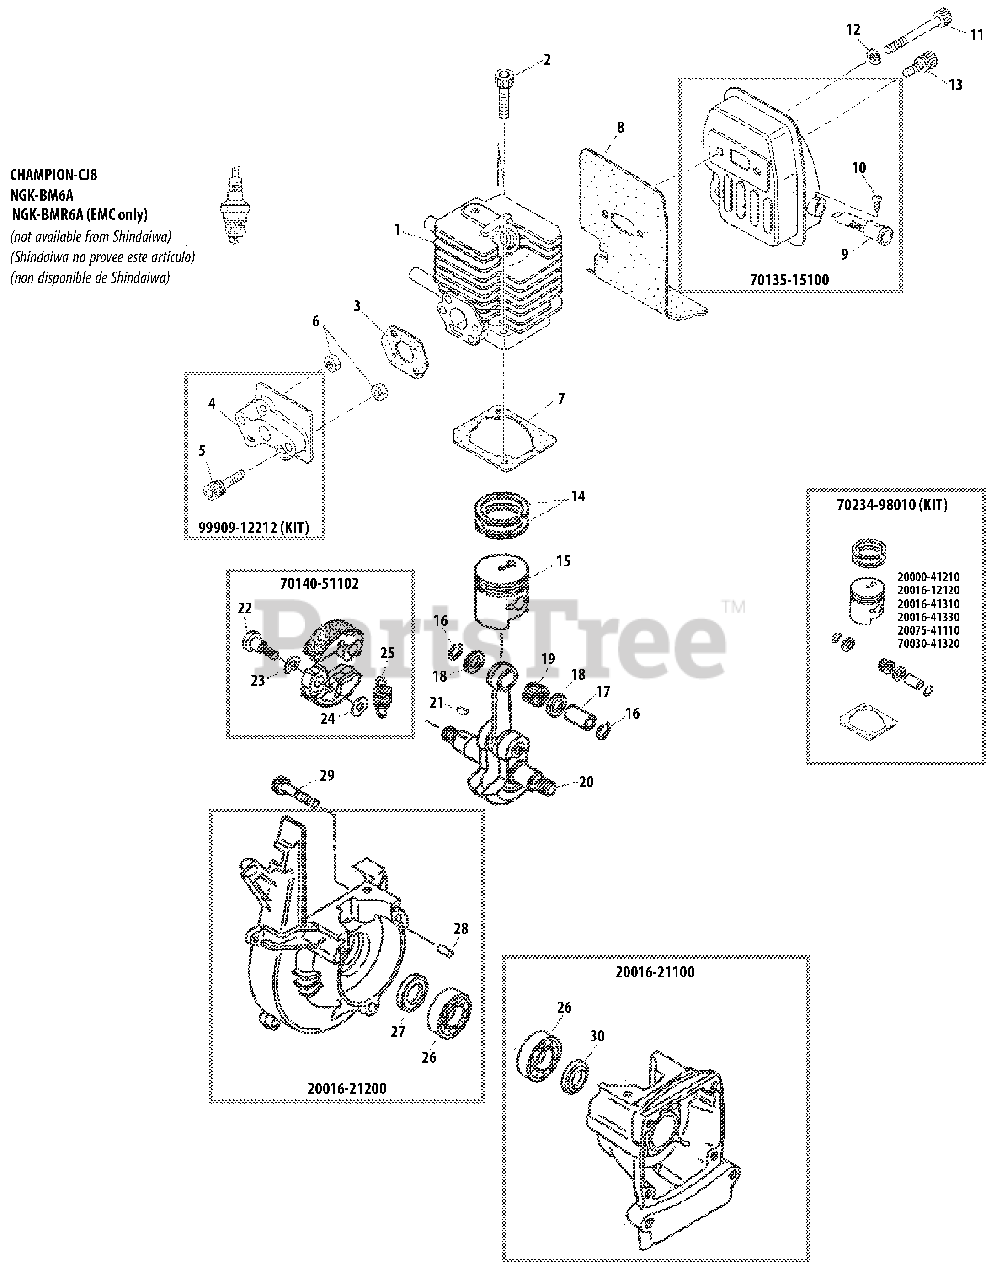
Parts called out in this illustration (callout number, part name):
1	CYLINDER
2	BOLT 5×25
3	GASKET, INTAKE
4	INSULATOR
5	BOLT SS M5×30
6	NUT M5×6.3
7	GASKET, CYLINDER
8	GASKET, EXHAUST
9	SCREEN, SPARK ARRESTER
10	SCREW, TAPPING 3×6
11	BOLT M5×50
12	WASHER, FLAT 5.5×10×0.8
13	BOLT 5×12
14	RING, PISTON
15	PISTON
16	RING, SNAP
17	PIN, PISTON
18	WASHER, THRUST
19	BEARING, NEEDLE
20	CRANKSHAFT
21	KEY, WOODRUFF 3×10
22	BOLT, CLUTCH
23	WASHER, SPRING
24	WASHER 6 MM
25	SPRING, CLUTCH
26	BEARING, BALL 6001 C3
27	SEAL, OIL 12
28	PIN, LOCATING Ø4×8
29	BOLT 5×25
30	SEAL, OIL 12
20016-21100	CRANKCASE ASSY, S
20016-21200	CRANKCASE ASSY, M
70135-15100	MUFFLER ASSY
70140-51102	CLUTCH ASSY
70234-98010	PISTON ASSY
99909-12212	INSULATOR ASSY
